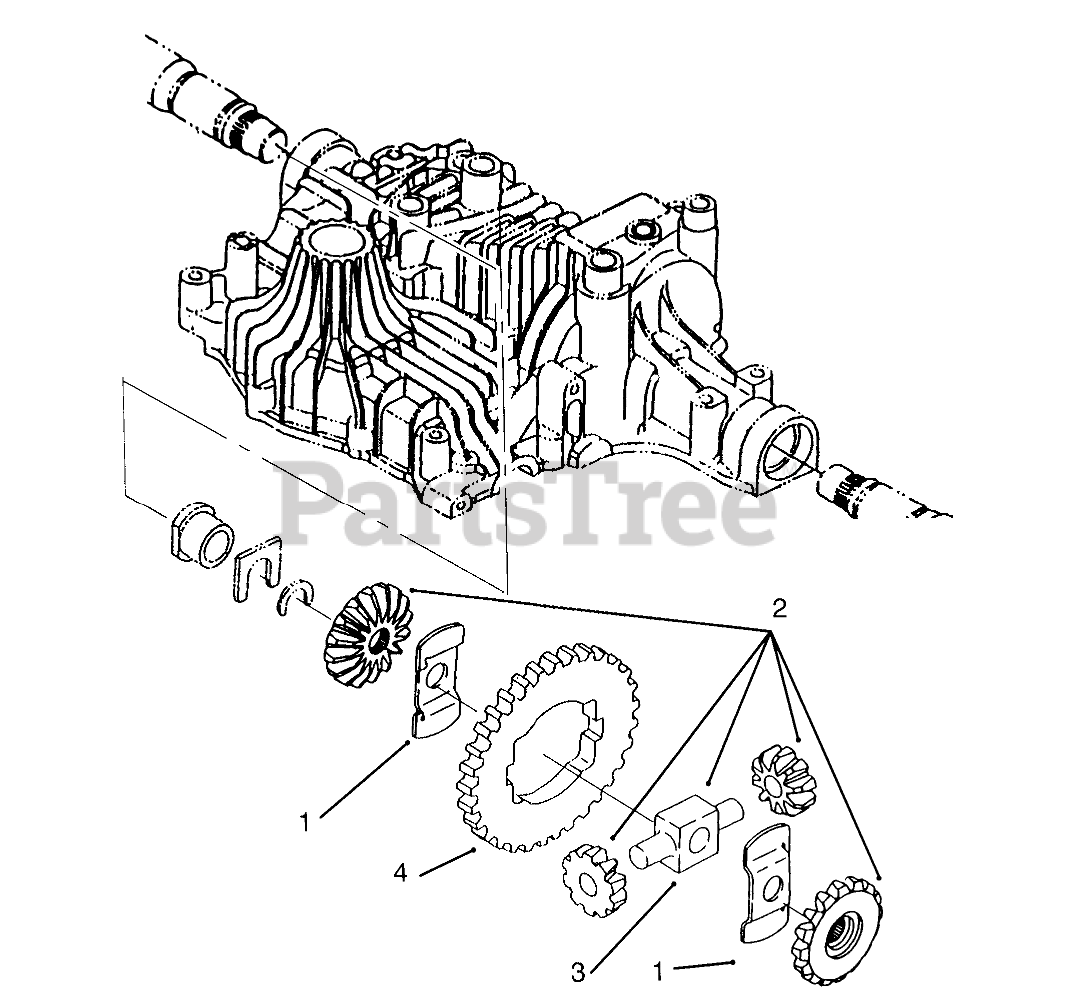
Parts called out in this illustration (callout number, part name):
1	Washer-Thrust (Only On: 72043,72063,72103)
2	Differential Gear ASM (Only On: 72043,72063,72103)
3	Shaft-Pinion (Only On: 72043,72063,72103)
4	Gear-Final (Only On: 72043,72063,72103)
